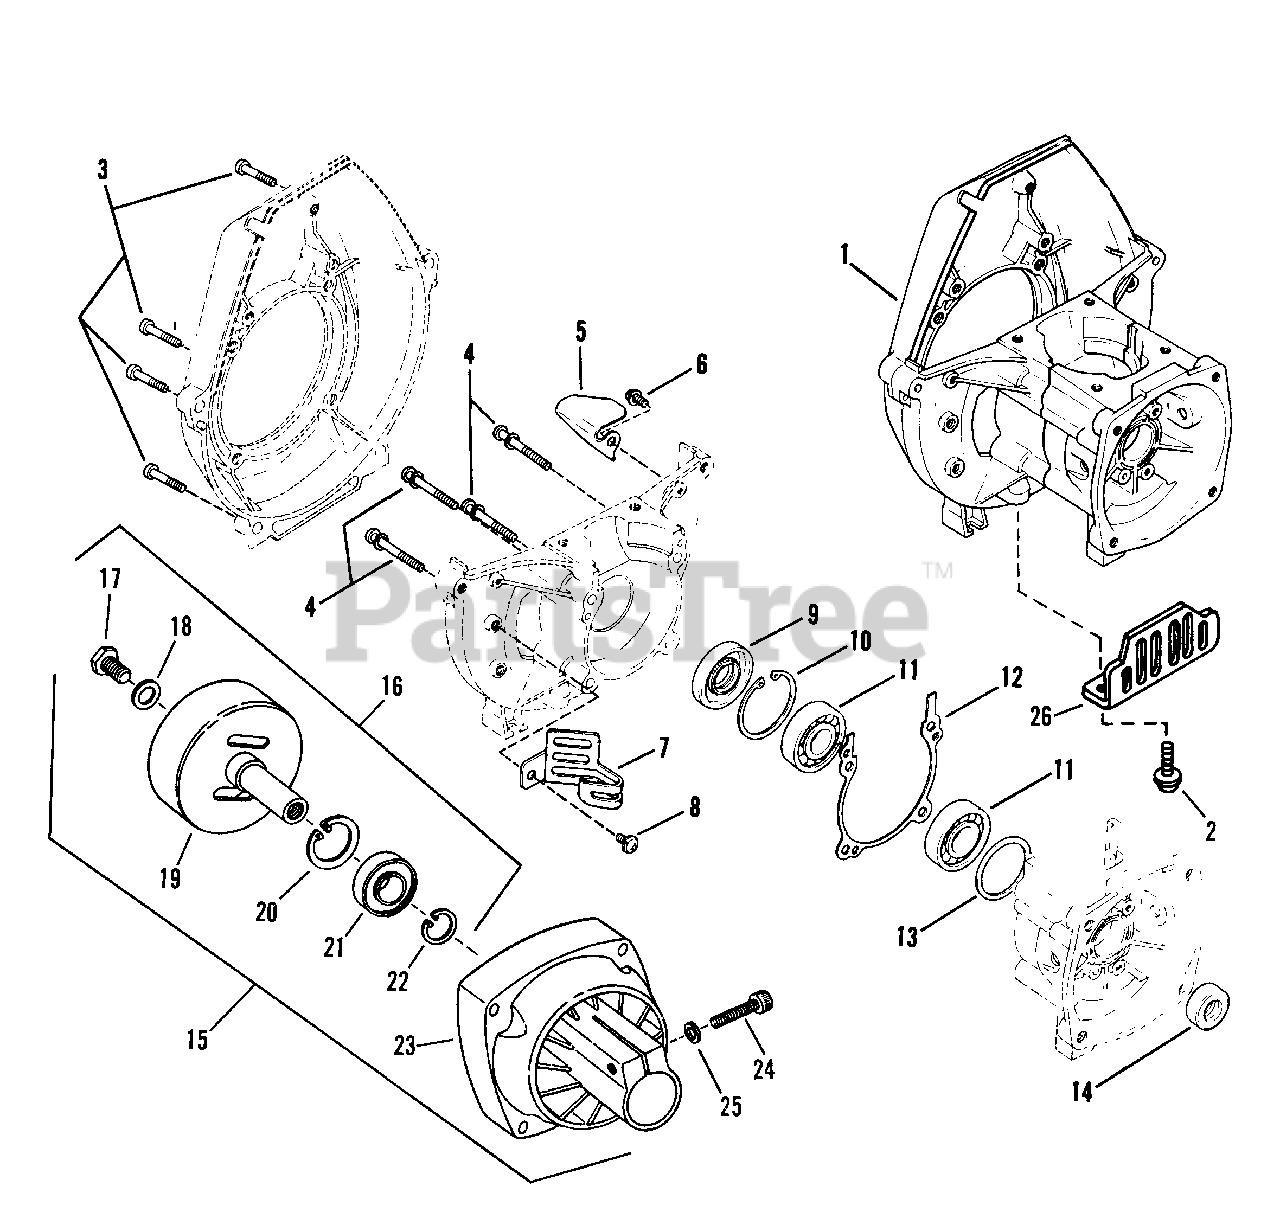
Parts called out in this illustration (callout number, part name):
1	CRANK CASE ASSM'Y
2	SCREW, M6 x 10mm Cross Hd.
9	SEAL, Oil
10	SNAP-RING
11	BEARING
12	GASKET, Crankcase
13	SHIM (Set of 3)
14	SEAL, Oil
15	ASSEMBLY, Clutch Case
16	ASSEMBLY, Clutch Drum
17	BOLT, Hex HD
19	DRUM, Clutch
20	RING, Snap
21	BEARING
22	RING, Snap
23	CASE, Clutch
24	SCREW, M6 x 25mm Socket
25	WASHER, M6 Split Lock
26	PLATE, Guard
